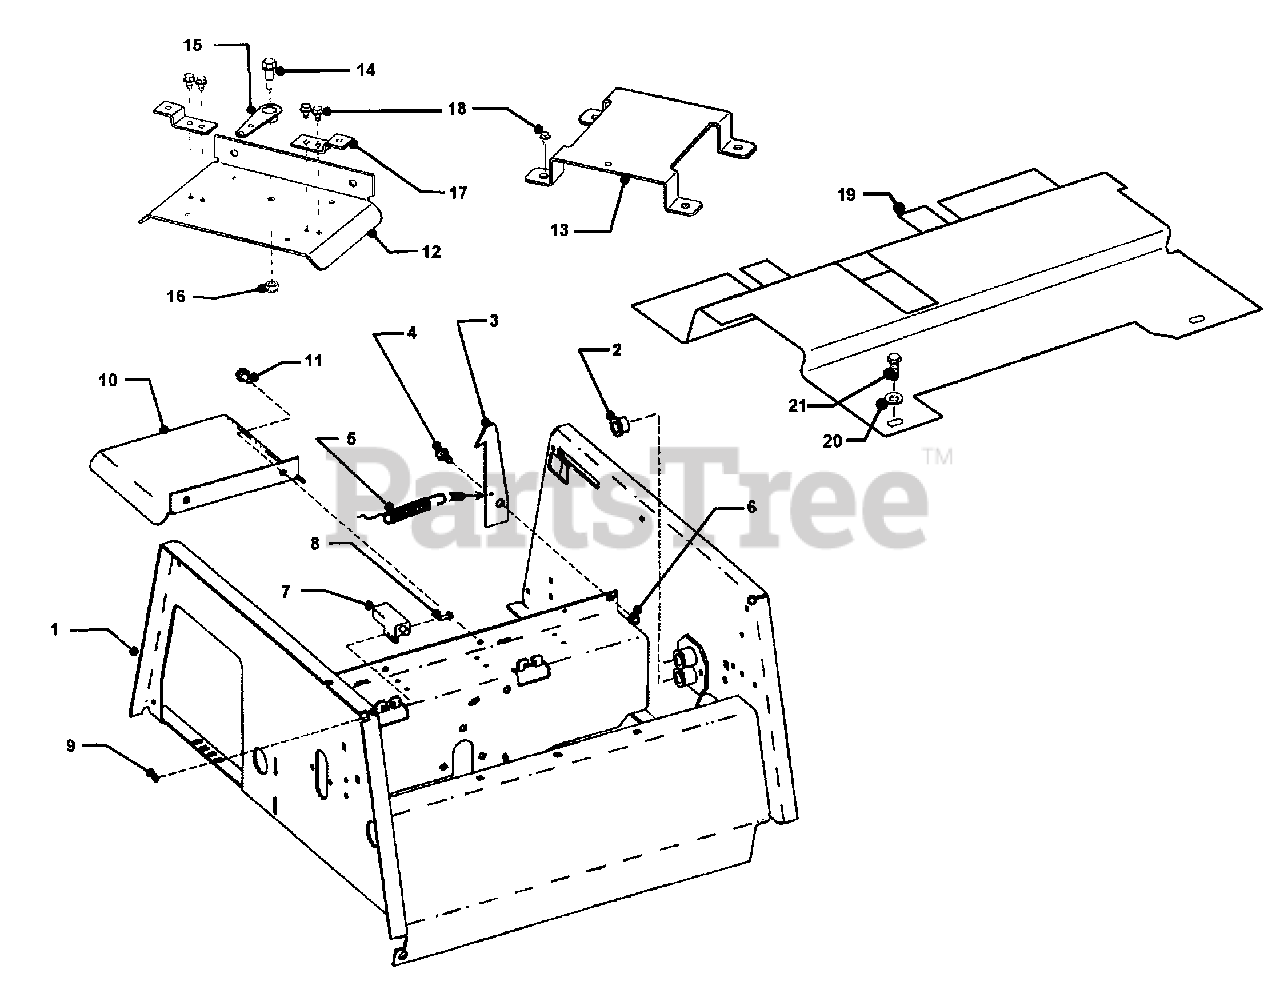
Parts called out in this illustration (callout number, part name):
1	UPPER CHASSIS
2	BUSHING, 5/8"
3	LATCH, Seat Support
4	BOLT, 5/16-18 Shoulder
5	SPRING
6	NUT, 5/16-18 HEX NYLON LOCK
7	SWITCH, DPDT
8	SCREW, #10-32 x 5/8" Gr. 5
9	NUT, #10-32 Hex Nyloc
10	GUARD, Driveshaft
11	SCREW, 5/16-18 x 5/8" Hex
12	GUARD, Driveshaft
13	COVER, Cable
14	BOLT, 5/16-18 Shoulder
15	LEVER, Cable Control
16	NUT, 5/16-18 HEX NYLON LOCK
17	BRACKET, Cable Anchor
18	SCREW, 1/4-20 x 3/8" Self-Tap
19	SHIELD, Drive
20	WASHER, 1/4 Flat
21	SCREW, 1/4-20 x 5/8" Self-Tap
